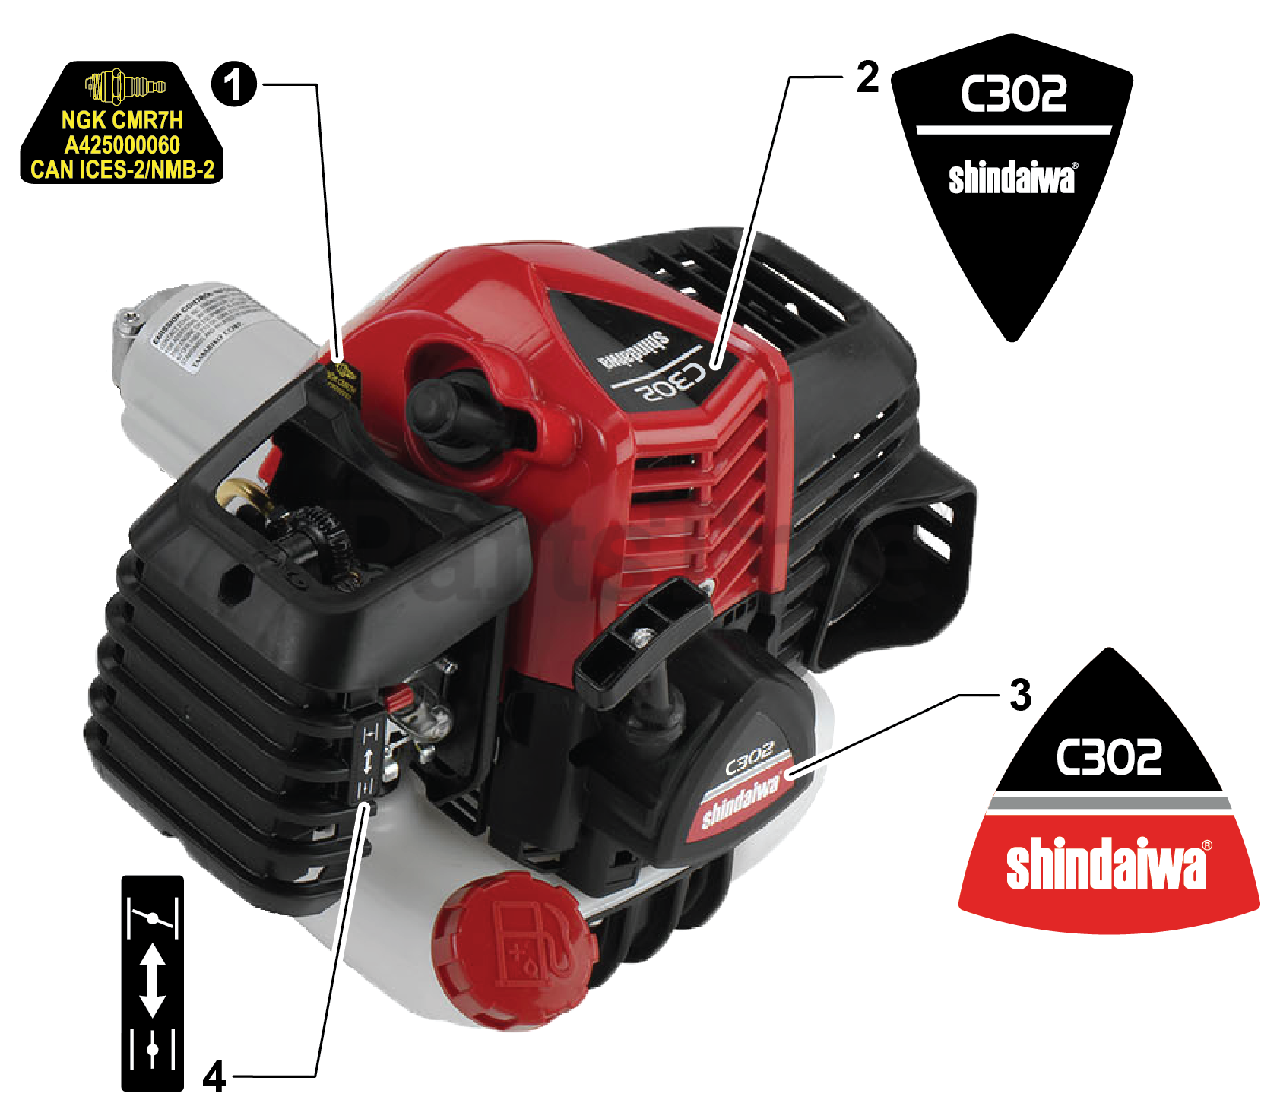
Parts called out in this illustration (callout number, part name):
1	LABEL - SPARK PLUG - CMR7H
2	LABEL - MODEL C302
3	LABEL - STARTER - C302
4	LABEL - CHOKE
